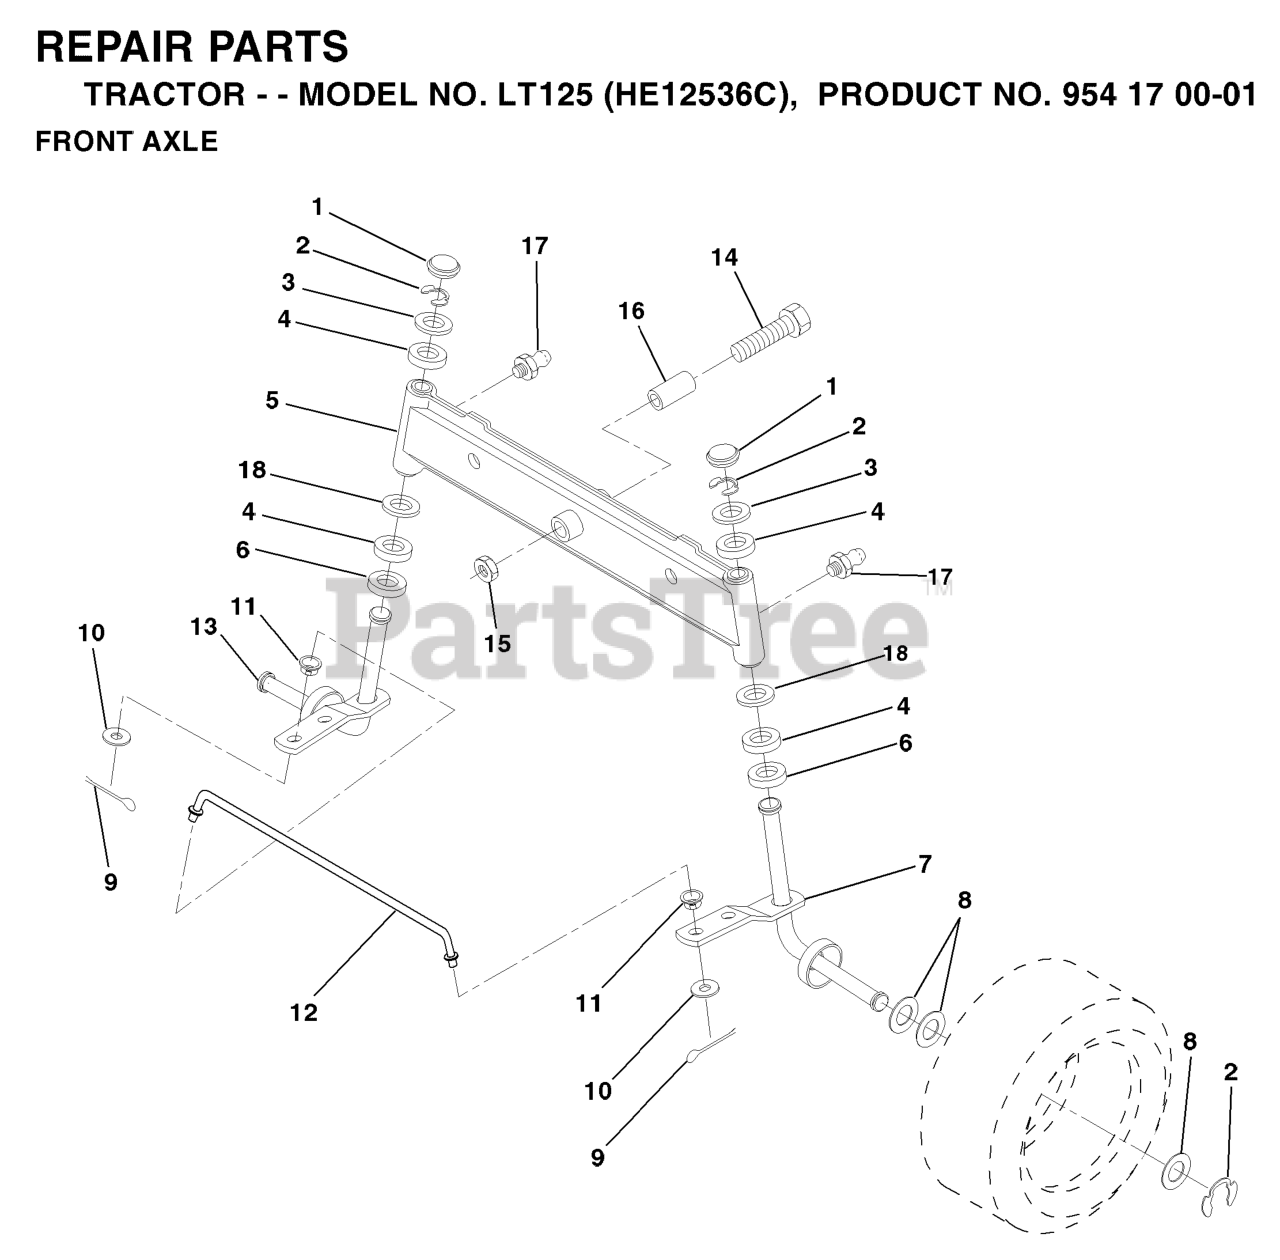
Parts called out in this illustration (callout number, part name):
1	CAP.SPINDLE.BLACK
4	BRNG T
6	THRUST WASHER
9	COTTER PIN
10	WASHER
11	BUSHING.DRAGLINK (2 2)
12	TIE ROD
13	SPINDLE.ASSEM.LH
14	Bolt, Hex Head 5/8-11 x 3-1/2
15	NUT-LOC,FLANGE LT
16	BEARING
17	ZERK M
